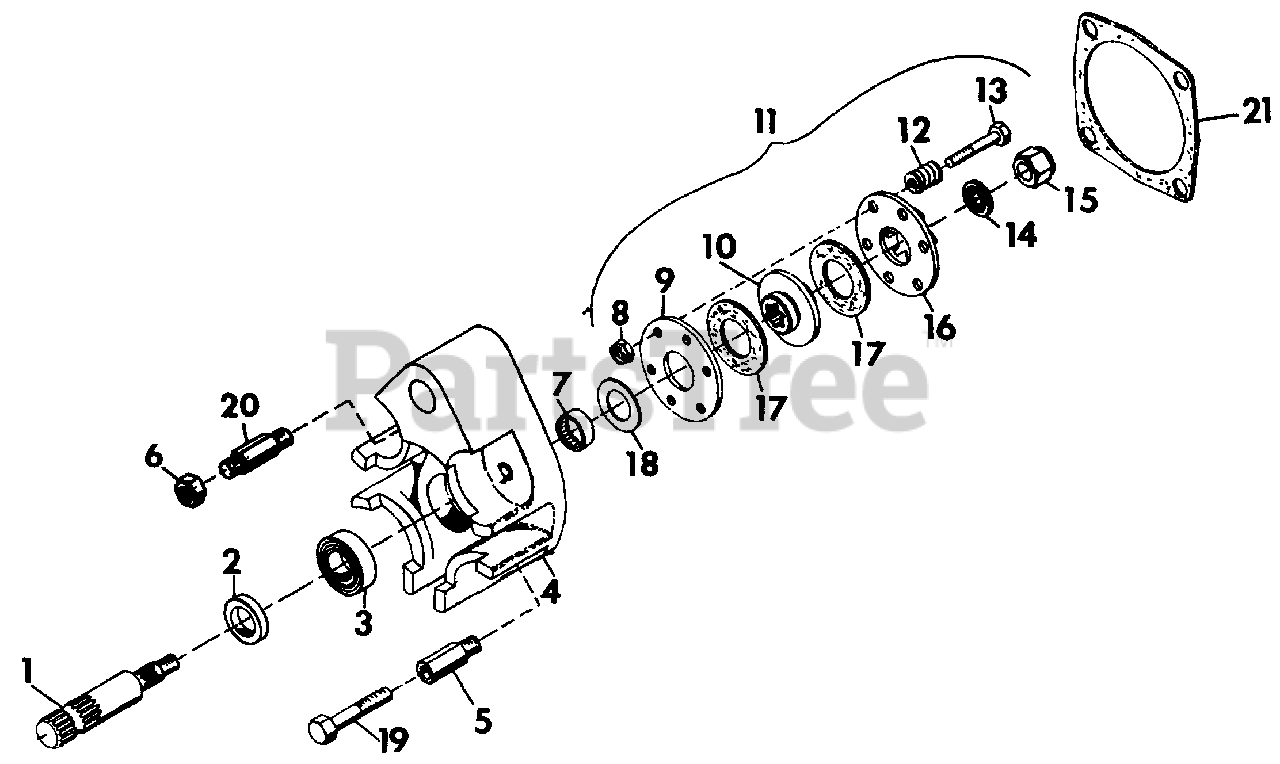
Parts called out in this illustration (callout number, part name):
1	Shaft, Quick Hitch
2	Ring, Retaining
3	Bearing, Ball 1.000 x 2.000 x .562
4	Adapter, Quick Hitch
5	Stud, Quick Hitch
6	Nut, Hex 1/2-13
7	Bearing, Needle 1.000 x 1.250 x .500
8	Nut, Lock 5/16-24
9	Plate, Back
10	Plate, Drive
11	Assembly, Clutch Attachment
12	Spring, Compression 3/4 x 2200 Lb/in
13	Bolt, Hex 5/16-24 x 1.75
14	Washer, Flat .656 x 1.312 x .095
15	Nut, Lock 5/8-24
16	Plate, Dog
17	Washer, Friction
18	Bearing, Thrust 1.012 x 1.750 x .125
19	Bolt, Hex 1/2-13 x 1.0
20	Stud, Quick Hitch
21	Gasket, Attachment
